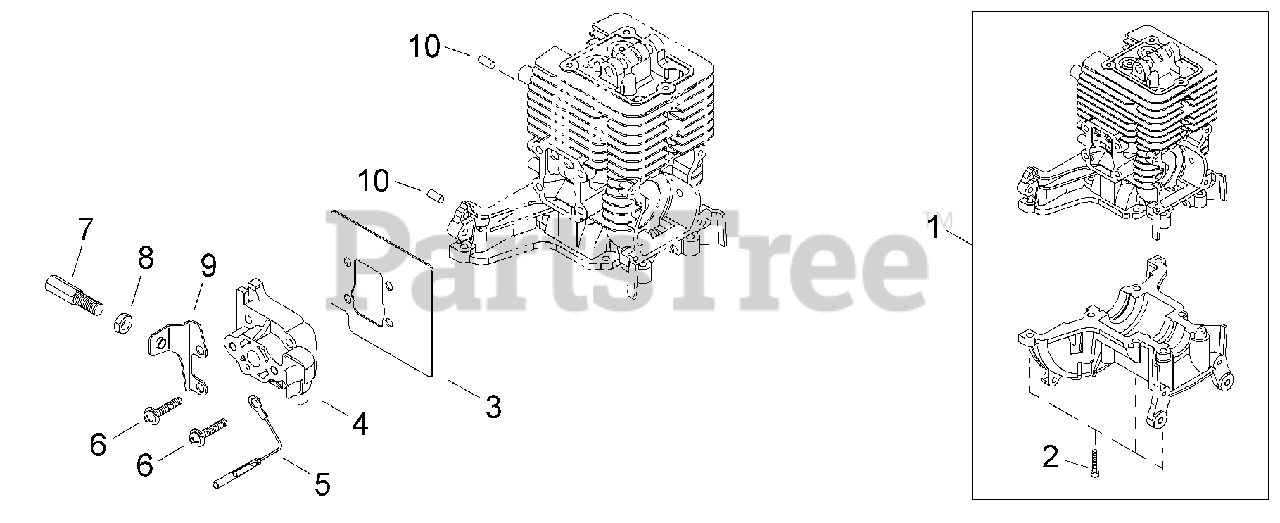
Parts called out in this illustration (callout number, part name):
1	CYLINDER & CRANKCASE ASSY
2	BOLT 5×16
3	HEAT SHIELD, INTAKE
4	INSULATOR WITH REED VALVE
5	LEAD - GROUND L= 110 MM
6	SCREW M5×25
7	ADJUSTER, THROTTLE CABLE
8	NUT, ADJUSTER LOCK M6
9	BRACKET, THROTTLE CABLE
10	PIN, LOCATING Ø4×8
